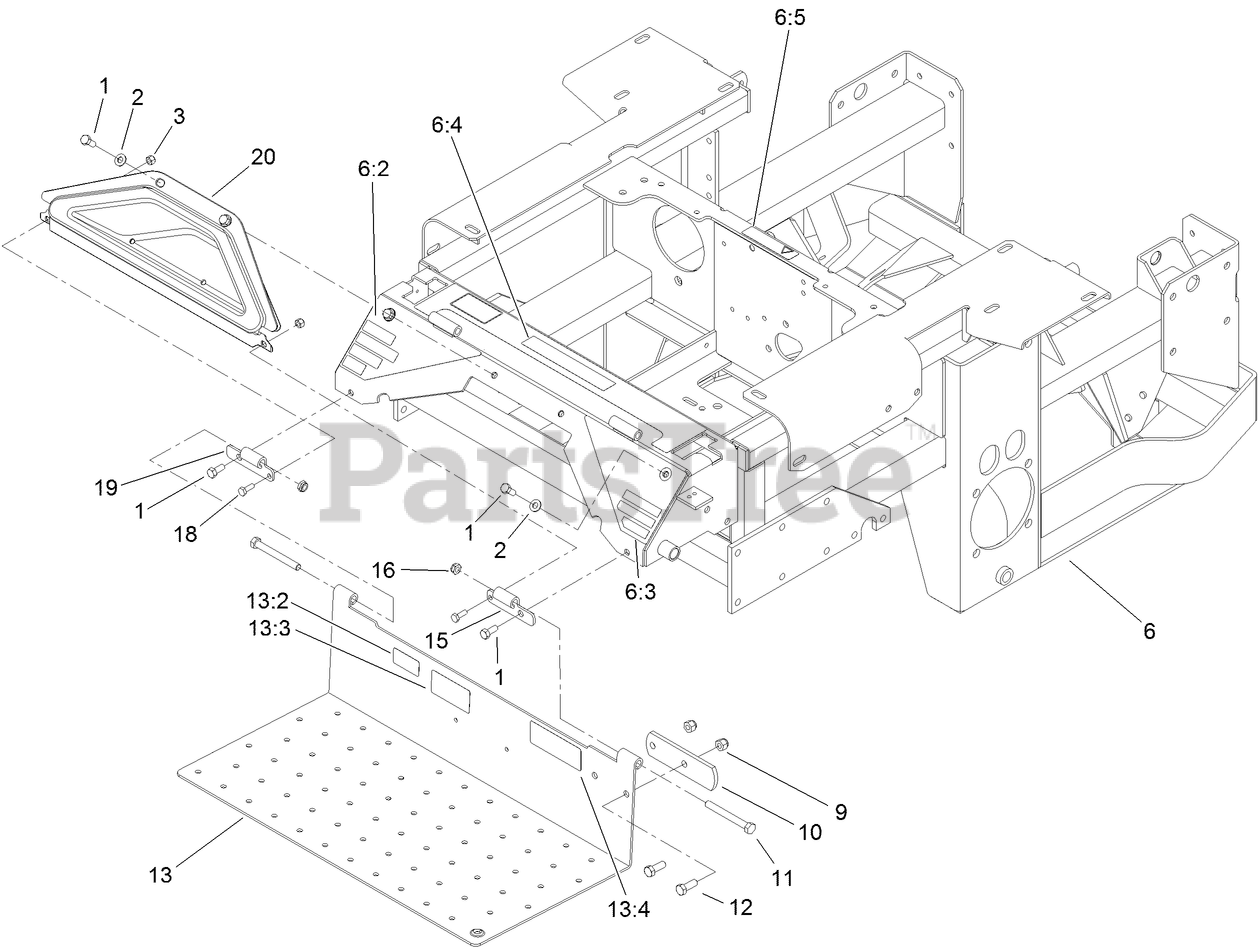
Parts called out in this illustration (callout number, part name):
1	SCREW-HH
2	WASHER-FLAT
3	NUT-LOCK, NI
6	ENGINE FRAME ASM
6:2	DECAL-WARNING
6:3	DECAL-DANGER
6:4	DECAL-CONSOLE, TOP
6:5	DECAL-COVER, MISSING
9	NUT-LOCK, NI
10	STOP-BRAKE, PARK
11	SCREW-HH
12	SCREW-HH
13	FLOOR PAN ASM
13:2	DECAL-PROTECTION, EAR
13:3	DECAL-LOCATION, MANUAL
13:4	DECAL-DIESEL, BIO-READY
15	HINGE-FLOORPAN, LH
18	SCREW-HH
19	HINGE-FLOORPAN, RH
20	POCKET
